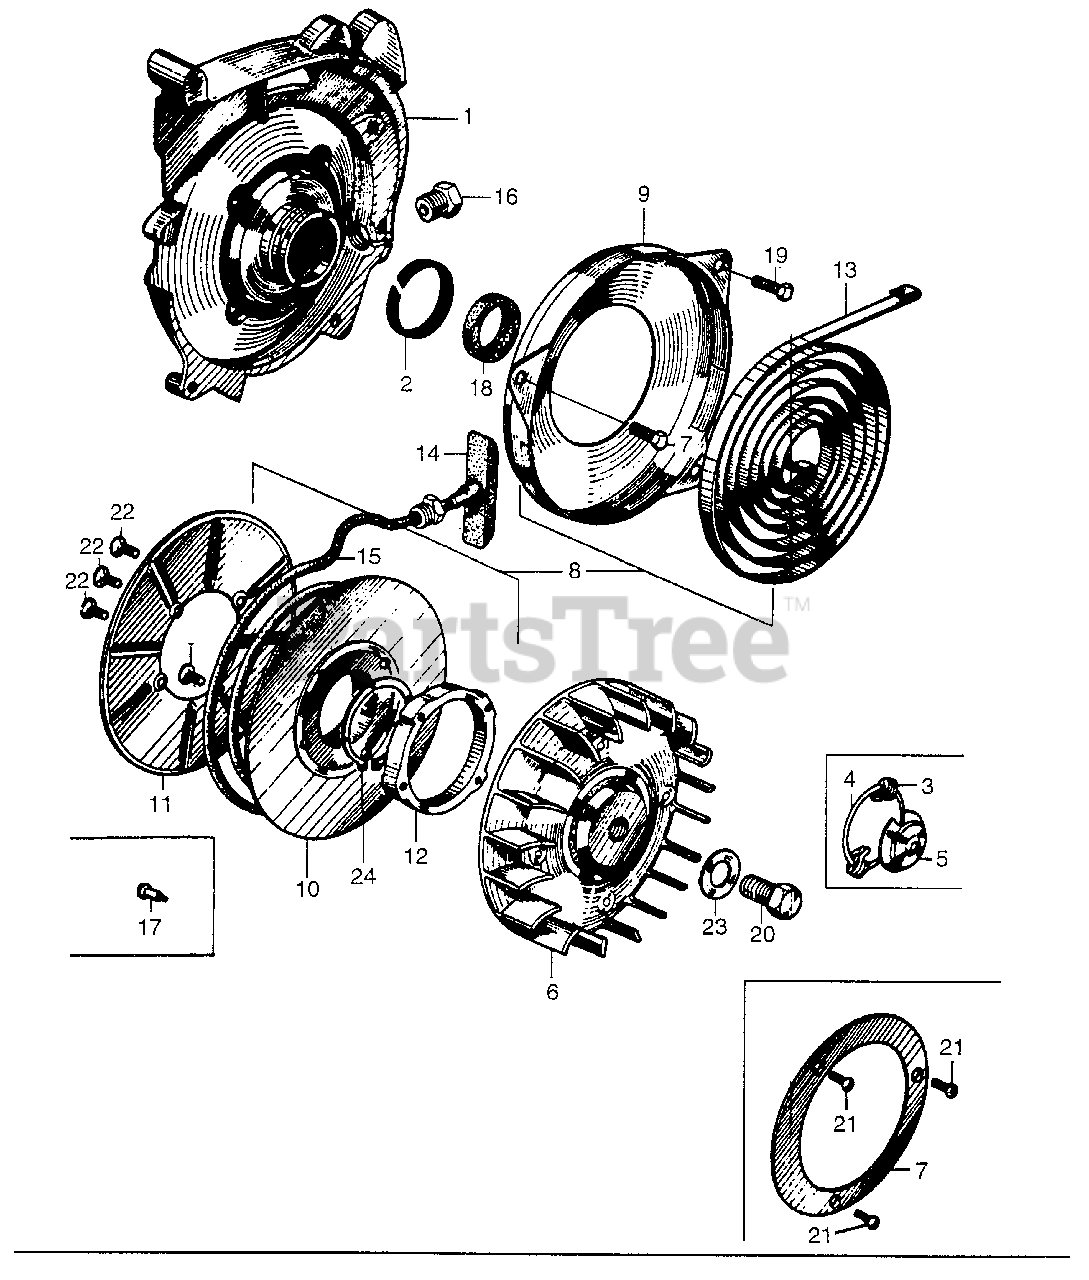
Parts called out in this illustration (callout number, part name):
1	CASE, SPRING
1	CASE, SET SPRING
2	FELT (5.5MM)
2	FELT (5.5MM) (NOT AVAILABLE)
3	WEIGHT, GOVERNOR (NOT AVAILABLE)
4	RING, GOVERNOR
5	SLIDER, GOVERNOR (NOT AVAILABLE)
6	FAN, COOLING
6	FAN, COOLING (NOT AVAILABLE)
7	PLATE, COOLING FAN
10	PULLEY, STARTER
11	PLATE, STARTER
12	RATCHET, STARTER (NOT AVAILABLE)
13	SPRING, STARTER (NOT AVAILABLE)
14	GRIP, STARTER (NOT AVAILABLE)
15	ROPE, RECOIL STARTER (#4X55")
15	ROPE, STARTER (#4X65")
15	ROPE (#4X55")
16	GUIDE, STARTER ROPE (NOT AVAILABLE)
17	BOLT, SPECIAL (4MM)
21	SCREW, FLAT (4X8) (NOT AVAILABLE)
22	SCREW, FLAT (5X16)
23	WASHER, PLAIN (10MM)
24	CIRCLIP (OUTER) (21MM) (NOT AVAILABLE)
24	CIRCLIP (OUTER) (18MM)
